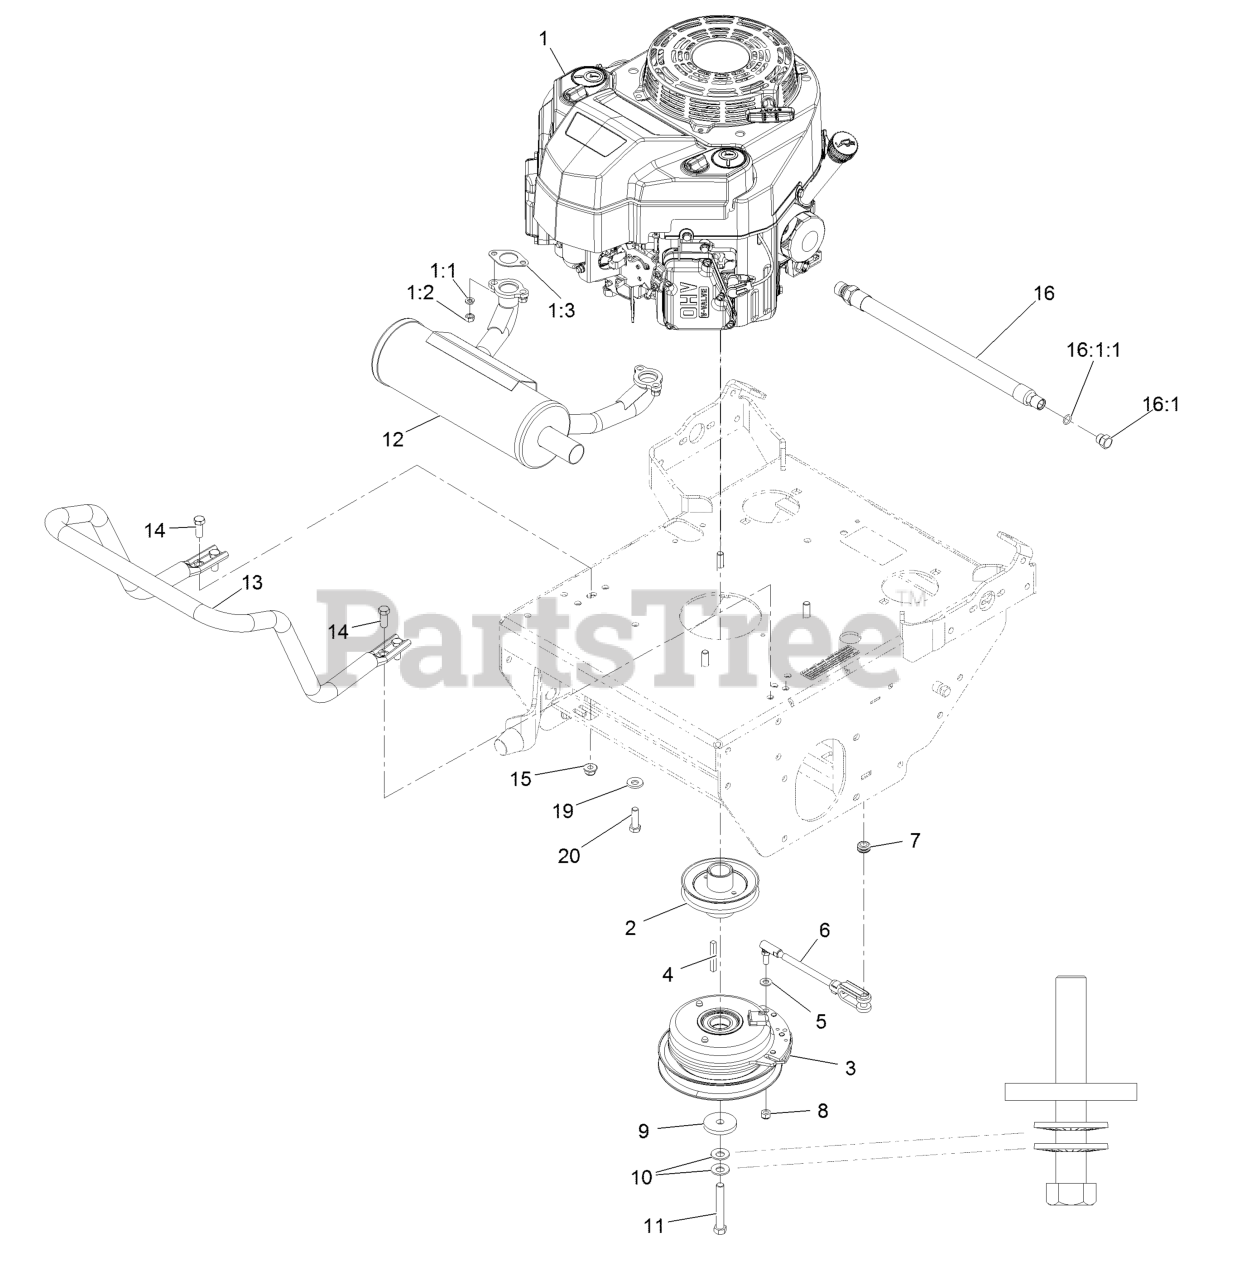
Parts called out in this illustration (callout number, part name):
1:1	Washer-Spring Lock M8
1:3	Gasket-Exhaust
2	Sheave, W/ Hub
3	Clutch, 105 Ft/Lbs, 1.13
4	Key-Machine 1/4 X 1/4 X 2
5	Washer-5/16 SAE
6	ASM, Clutch Anchor
7	Grommet
8	Nut-Lock 5/16-24
9	Washer-Clutch
10	Washer-Spring Disc 7/16
11	Screw-HH 7/16-20 X 3
12	Muffler-Horizontal
13	Guard-Muffler
14	Screw-HH 3/8-16 X 1
15	Nut-Nyloc 3/8-16 Flg
16	Asm-Oil Drain Hose W/Plug
16:1	Plug-W/O-Ring
16:1:1	O-Ring
19	Washer-Spring Disc 3/8
20	Screw-HH 3/8-16 X 1 1/4
